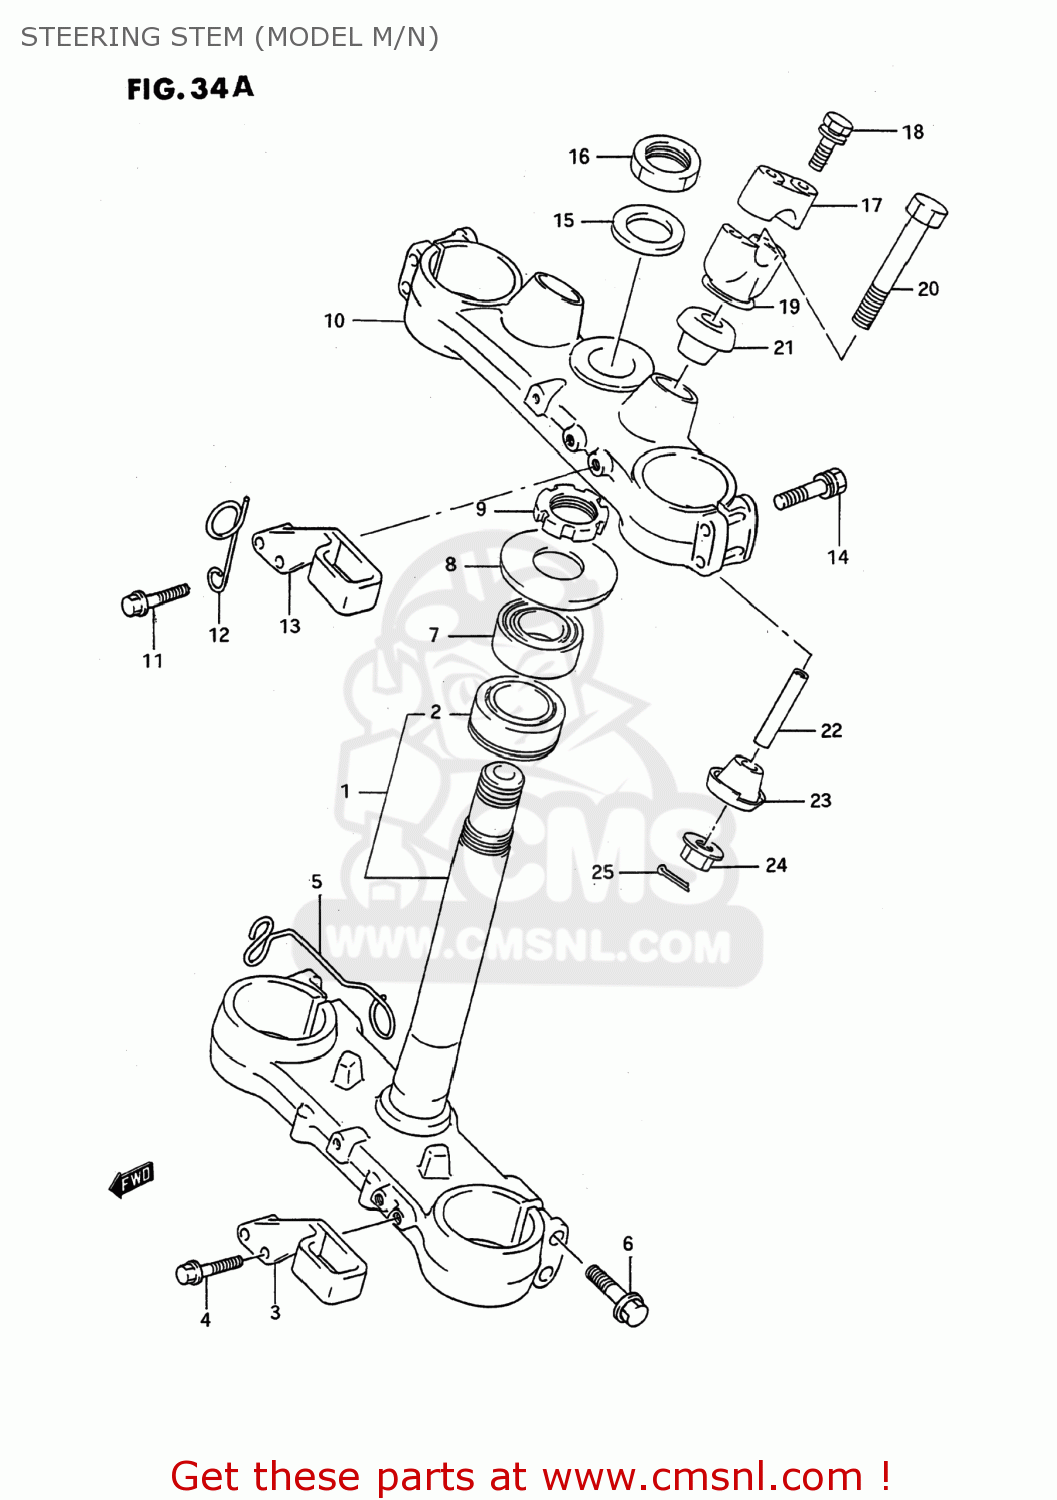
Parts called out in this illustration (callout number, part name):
1	STEM,STEERING
2	BEARING(30X52X16)
3	GUIDE,CLUTCH CABLE
4	BOLT,GUIDE
5	GUIDE,SPEEDOMETER CABLE
6	BOLT,STEM 8X45
7	BEARING
8	SEAL,STEERING,UPPER DUST
9	NUT,STEERING
10	HEAD,STEERING STEM
11	BOLT,GUIDE
12	GUIDE,CLUTCH CABLE
13	GUIDE,HOSE
14	BOLT,STEM 8X45
15	WASHER,STEM HEAD
16	NUT,STEM HEAD
17	HOLDER,HANDLEBAR
18	BOLT,HANDLE HOLDER(8X35)
19	HOLDER,HANDLE UNDER
20	BOLT,LWR HOLDER
21	CUSHION,RUBBER UPR
22	SPACER
23	CUSHION,RUBBER UNDER
24	NUT
25	COTTER PIN
